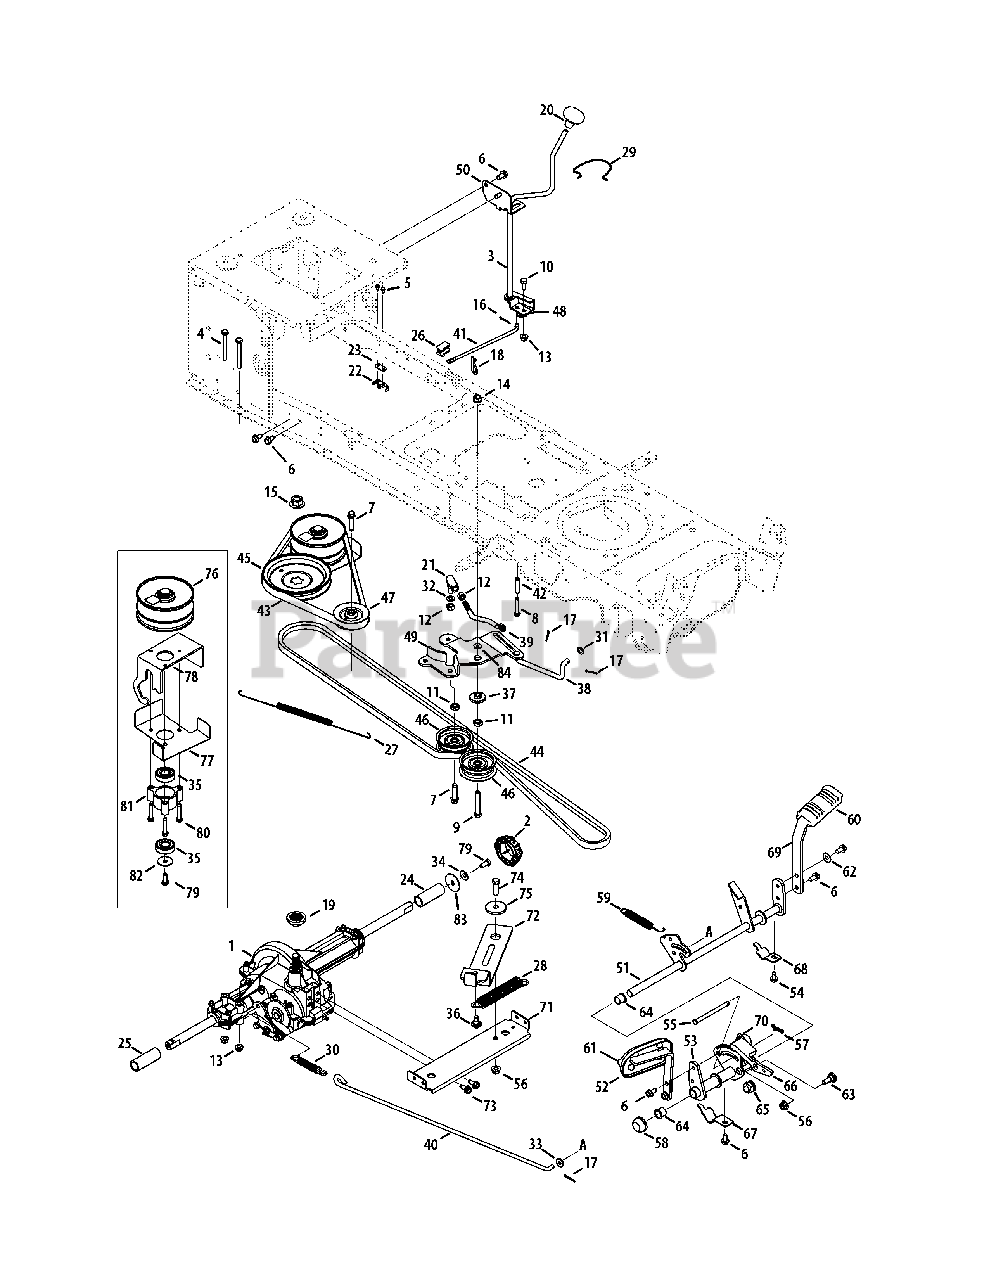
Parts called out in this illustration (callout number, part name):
1	Transaxle Ass’y
2	Cap, Hub
3	Lever Ass’y, Shift
4	Hex Screw, 5/16-18, 2.75, Gr5, Std
5	Screw, Ab, #8-18, 0.500,
6	Screw, Self-tapping, 5/16-18, .750
7	Screw, Sems, 3/8-16, 1.500
8	Screw, Self-tapping, 1/4-20, 1.750
9	Hex Screw, 3/8-16, 2.25, Gr5, Std
10	Hex Screw, 5/16-18, .625, Gr5, Std
11	Nut, Jam, 7/16-20, Gr2
12	Nut, Hex, 3/8-24, Gr5
13	Nut, Flange Lock, 5/16-18, Grf
14	Nut, Flange Lock, 3/8-16, Grf
15	Nut, Flange, 9/16-18, Gr2
16	Pin, Cotter, .072 Dia. x 1.13
17	Pin, Cotter, 3/32, 1.0
18	Pin, Cotter Internal, .125 Dia
19	Hub, Pulley, 5/8 Spline
20	Knob, Shift
21	Ball, Joint
22	Switch, Spring, Short
23	Plate, Insulator Nut
24	Sleeve, .758 x .821 x 3.3125
25	Sleeve, .758 x .821 x 2.4375
26	Bearing, Shift Plate
27	Spring, Extension, .70 Dia x 12.00
28	Spring, Extension, .97 OD x 6.18
29	Clip, Spring, Shifter
30	Spring, Extension, .59 OD x 4.00
31	Washer, Flat, .385 x .62 x .063
32	Washer, Lock, 3/8, Regular Duty
33	Washer, Flat, .344 x .750 x .120
34	Washer, Bell, .340 x .872 x .060
35	Bearing, Ball, 17x40x12, 6203, Ds
36	Screw, Shoulder, .43x.29, 5/16-18
37	Spacer, Shoulder, 1.375 x .380 x .183
38	Rod, Footpedal Bypass
39	Rod, Adjustment, Idler, 3/8
40	Rod, Brake
41	Rod, Shift,
42	Spacer, .260 x .372 x 1.420
43	Belt, V-Type, Poly
44	Belt, V-Type, Poly
45	Pulley, V-Type, 7.25 Dia Spun
46	Pulley, Idler, Flat 2.75 OD
47	Pulley, Idler, V-Type x 3.06
48	Bracket, Shift, Adjustment
49	Bracket, Idler, Center Double
50	Bracket, Shift, F-N-R
51	Control Ass’y, Brake
52	Ped Ass’y, Control, Auto Drive
53	Bracket Ass’y, Pedal
54	Screw, Self-tapping, 5/16-18, 0.625,
55	Pin, Clevis, 5/16 x 3.985
56	Nut, Flange Lock, 3/8-16, Grf,
57	Pin, Cotter, Bow-Tie 72
58	Cap, Push 5/8
59	Spring, Extension, .63 Dia x 4.95
60	Pad, Pedal, Brake
61	Pad, Control
62	Washer, Bell, .340 x .872 x .060
63	Bolt, Shoulder, .500 x .270, 3/8-16
64	Bearing, Flange
65	Bearing, Hex Flange, .628 ID, Split
66	Latch, Cruise
67	Bracket, Support, Pedal Strap
68	Bracket, Support, Pedal Strap 5/8
69	Bracket, Ped, Brake
70	Plate, Bracket, Reinforcement
71	Bracket Ass’y, Transmission
72	Bracket Ass’y, Idler
73	Screw, Self-tapping, 5/16-18, 0.750,
74	Hex Screw, 3/8-16, 1.25, Gr5, Std
75	Spacer, Shoulder, .8840 x .190
76	Pulley Ass’y, Var Spd, 4.75 OD
77	Keepr Ass’y, Belt
78	Bracket Ass’y, Variable
79	Hex Screw, 5/16-24, .750, Gr5, Lock
80	Screw, Self-tapping, 1/4-20, 1.500,
81	Cup, Bearing
82	Washer, Flat, .330 x 1.25 x .06,
83	Washer, Flat, .350 x 1.59 x .062
84	Wash, Flat, .385 x 1.00 x .03
